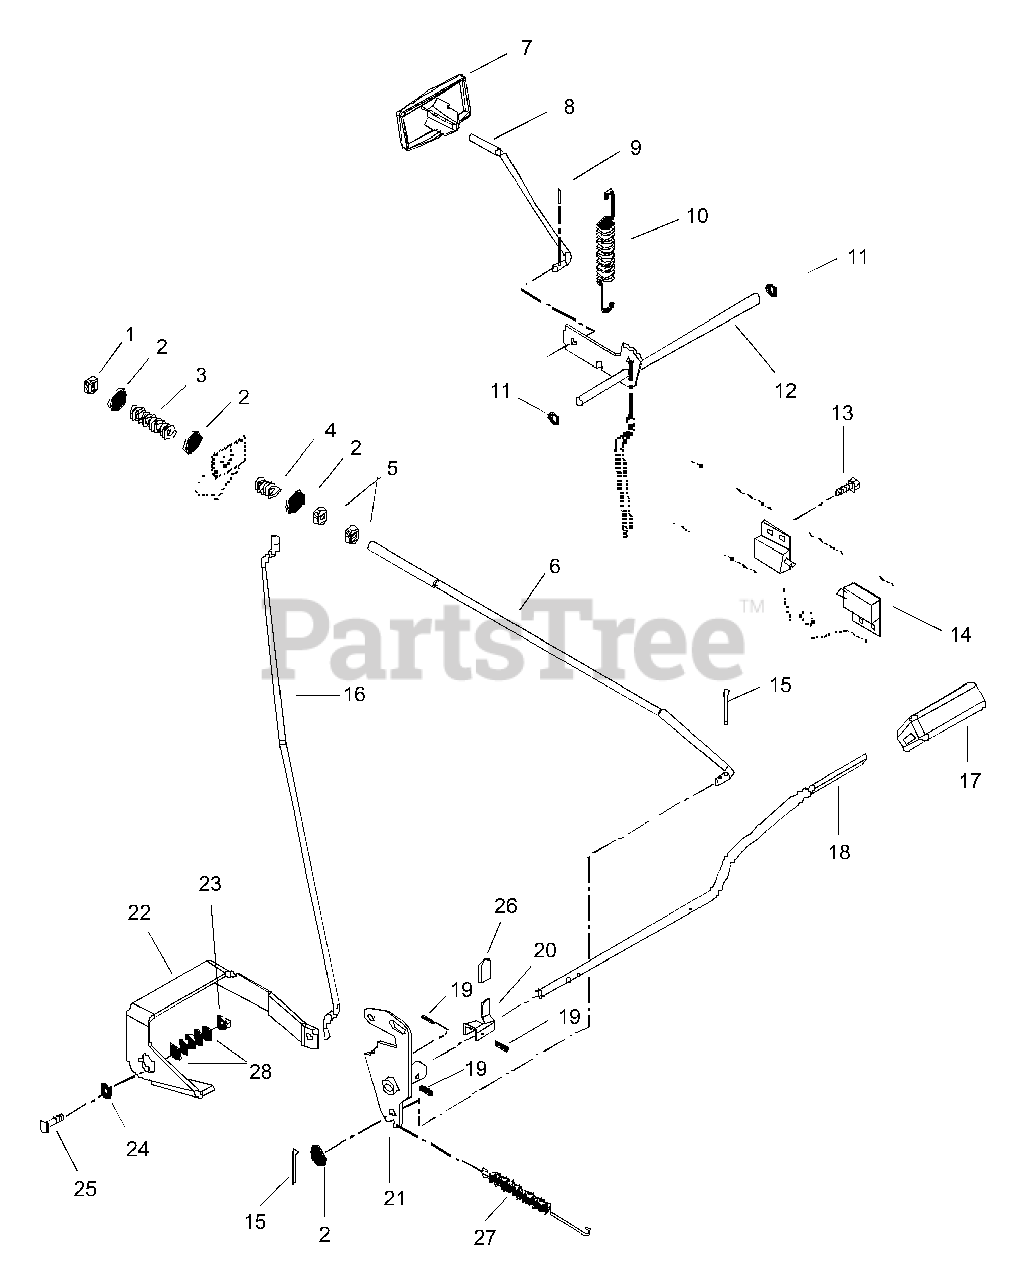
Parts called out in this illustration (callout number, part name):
1	Nut-Locking-Jam .375-16
2	Washer-Flat-Steel .406 x .812 x .065
3	Spring-Compression .048 x .59 x 2.06
4	Spring-Compression .125 x .78 x 1.00
5	Nut-Jam .375-16
6	Rod-Brake
7	Knob-Park Brake
9	Pin-Cotter .06 x .50
10	Spring-Tension .051 x .60 x 2.25
11	Ring-Retaining-External .250 x .010
12	Bellcrank-Parking Brake
13	Screw-Tapping 12-24 x .50
14	Switch-Single Pole N.O.
15	Pin-Cotter .09 x .75
16	Rod-Parking Brake
17	Cover-Pedal-Brake
18	Pedal-Brake
19	Pin-Groove .188 x 1.25
20	Lever-Brake Switch
21	Arm & Hub-Brake
22	Lever-Parking Brake
23	Nut-Locking-Center .312-18
24	Shoulder Spacer
25	Bolt-Round Head Square Neck .31-18 x .75
26	Grip .062 x .375 x .750
27	Spring-Tension .095 x .85 x 4.38
28	Washer-Plastic .390 x .875 x .062
